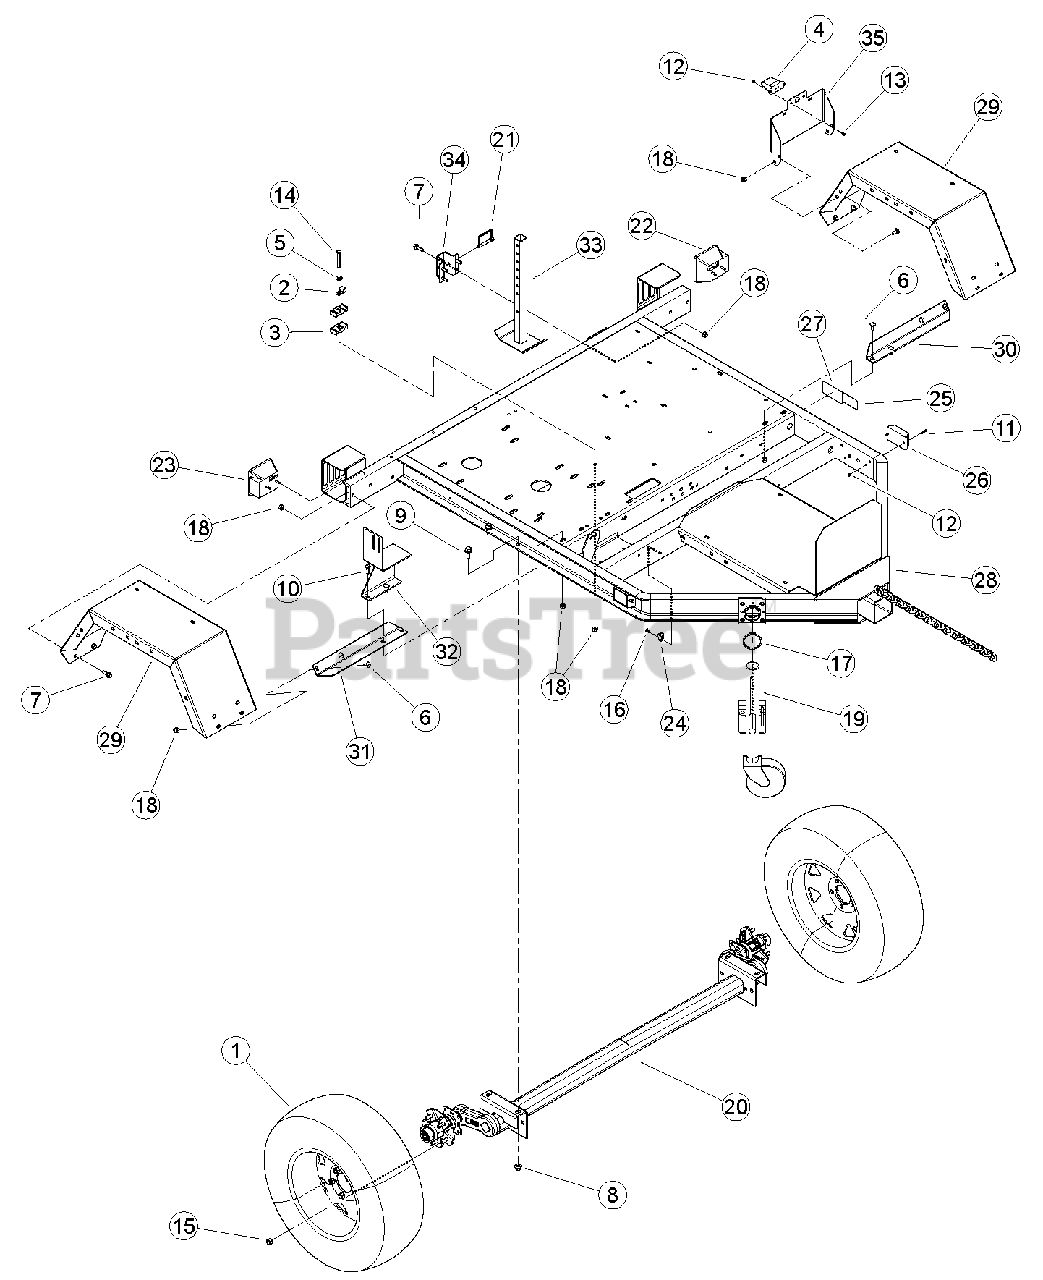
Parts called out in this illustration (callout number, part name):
1	ASSEMBLY, 15 INCH TIRE + WHEEL
2	CLAMP, 9/16 COATED
3	CLAMP, PLASTIC HOSE
4	LIGHT, LICENSE PLATE
5	WASHER, 3/8" FLAT ZP
6	BOLT, 3/8 X 1" GR5 CRG NC ZP
7	BOLT, 3/8 X 1-1/4 FLANGE NC
8	NUT, 1/2-13 NYLOCK FLANGE
9	BOLT, 1/2 -13 X 1-1/4 FLANGE NC
10	BOLT, 3/8 X 1-1/4" GR5 CRG NC ZP
11	SCREW, MCH 10-24 X 1" RND HD PHL ZP
12	NUT, 10/24 NYLOCK TYPE NM ZP
13	SCREW, MCH 10-24 X 1/2" PAN HD PH ZP
14	BOLT, 3/8 X 2-3/4" GR5 NC HHCS ZP
15	NUT, 1/2-20 WHEEL
16	RIVET, AL BLIND 1/4 X 3/4 DOME HEAD
17	SNAP RING, 2-1/2 EXTERNAL
18	NUT, 3/8-16 NYLOCK FLANGE
19	JACK, PIVOTING W/ SWIVEL CASTOR
20	AXLE, 3000 LB TORSION
21	PIN, 3/8 X 2-3/4" SNAP
22	LIGHT, LH TAIL
23	LIGHT, RH TAIL
24	CLAMP, CABLE MOUNT
25	DECAL, P215/70R15 LOAD RATING
26	LIGHT, AMBER MARKER
27	DECAL, EPA EMISSION
28	WELDMENT, CHIPPER TRAILER
29	FENDER, HEAVY DUTY
30	ANGLE, FENDER MOUNT LH
31	ANGLE, FENDER MOUNT RH
32	WELDMENT, BELT GUIDE
33	WELDMENT, REAR STABILIZER
34	GUIDE, TRAILER SUPPORT
35	BRACKET, LICENSE PLATE
